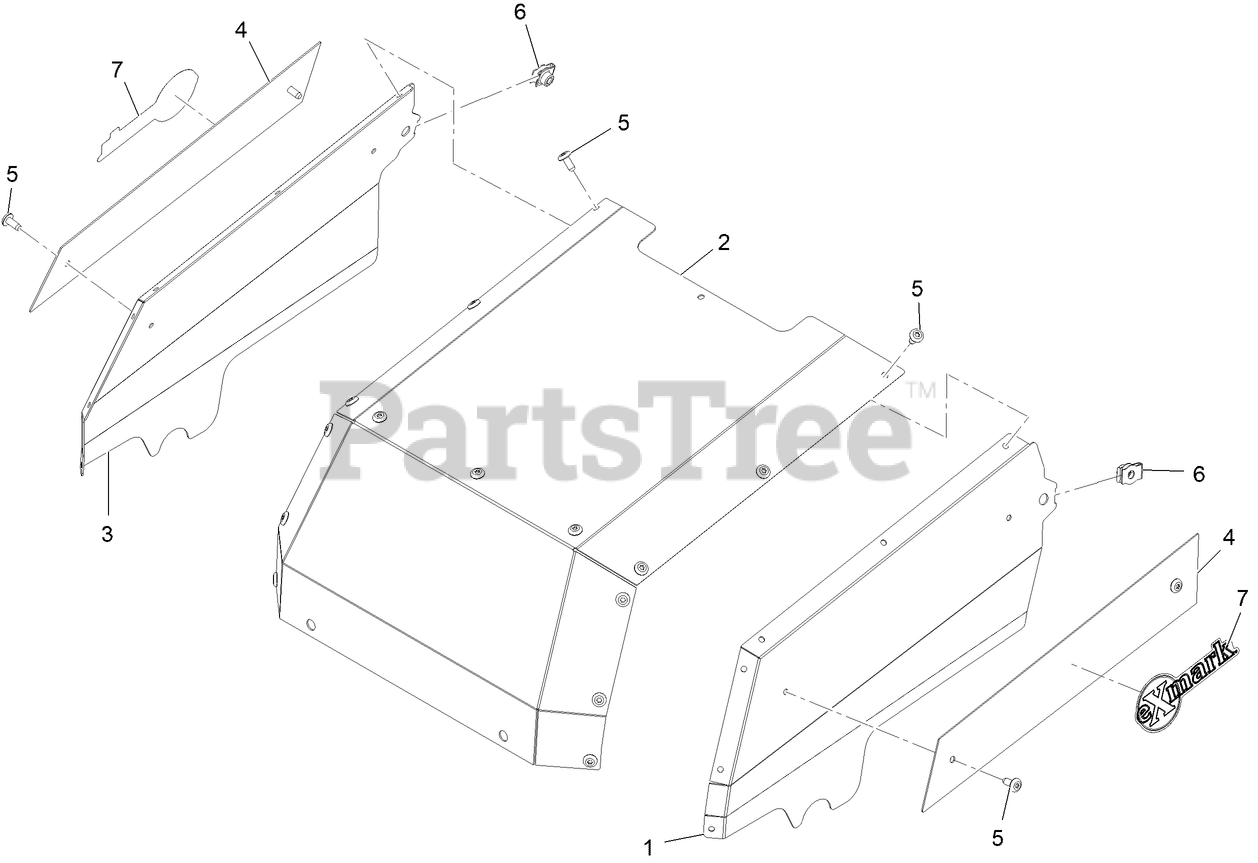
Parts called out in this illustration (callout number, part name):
1	COVER-BATTERY LH
2	PANEL-HOOD
3	COVER-BATTERY RH
4	PLATE- HOOD DECAL
6	NUT-TINNERMAN
7	DECAL-EXMARK LOGO
